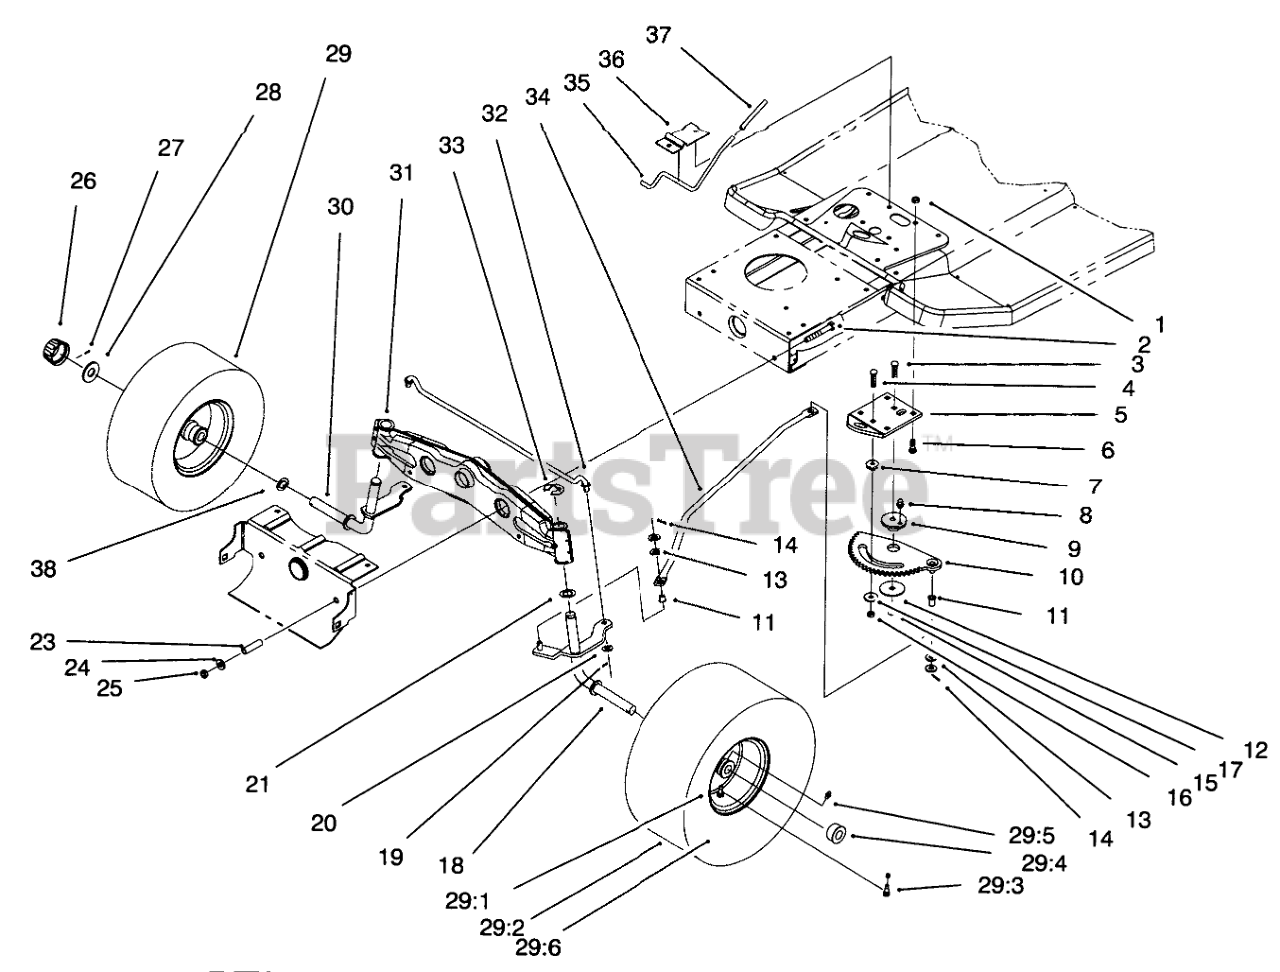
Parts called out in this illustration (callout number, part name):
1	NUT-LOCK, NI
2	SCREW-HH
3	SCREW-CARR
4	SCREW-CARR
5	BRACKET-RACK, STEERING
6	BOLT-CARR
7	SPACER-RACK, STEERING
8	FITTING-GREASE
9	BUSHING-ECCENTRIC
10	RACK-STEERING
11	BUSHING-FLANGED, NYLON
12	WASHER-BEARING
13	WASHER-FLAT
14	PIN-COTTER
15	NUT-LOCK, NI
16	NUT-LOCK, NI
17	WASHER-PIVOT
18	LH SPINDLE ASM
19	PIN-COTTER
20	WASHER-FLAT
21	WASHER-THRUST
23	SPACER
24	WASHER-FLAT
25	NUT-LOCK, NI
26	CAP-HUB
27	PIN-COTTER
28	WASHER-PLAIN
29	Front Wheel & Tire Assembly (Incl. Ref. #29:1-29:6)
29:1	RIM ASM
29:2	TIRE 15 X 6.00 X 6
29:3	Stem-Valve
29:4	BEARING-WHEEL
29:5	FITTING-GREASE
29:6	TUBE-INNER
30	RH SPINDLE ASM
31	FRONT AXLE ASM
32	TIE ROD-STEERING
33	E-RING
34	LINK-DRAG
35	ROD-BRAKE, PARKING
36	BRACKET-PARKING BRAKE
37	GRIP-BRAKE, PARKING
38	WASHER-THRUST
